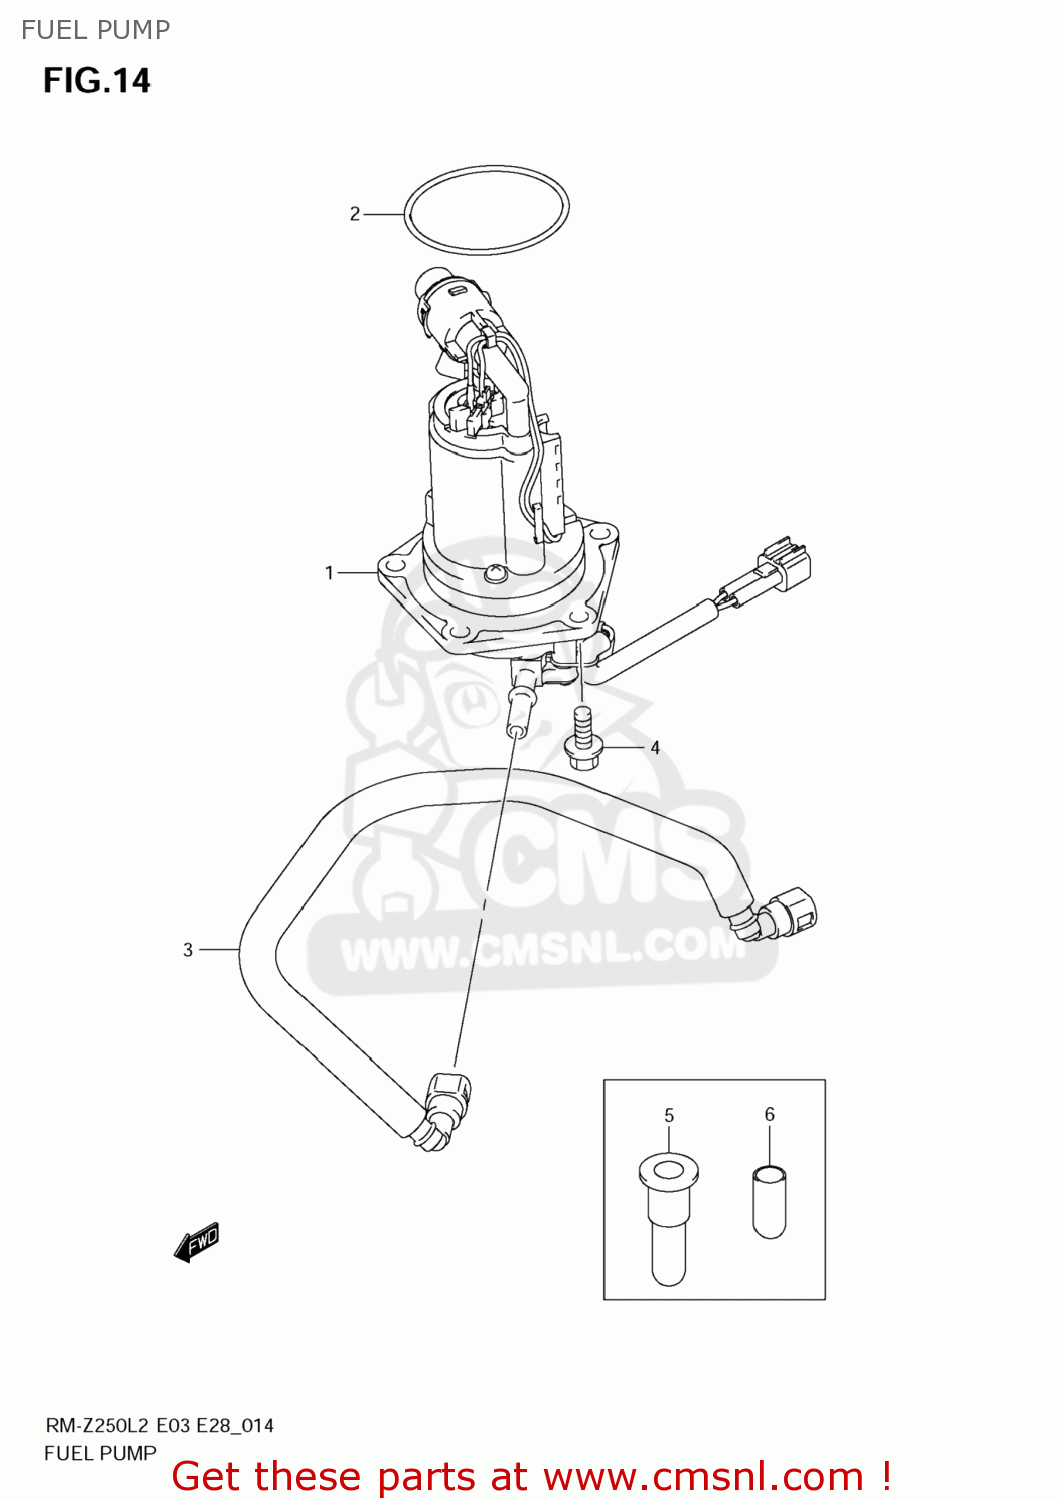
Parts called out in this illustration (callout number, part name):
1	PUMP ASSY,FUEL
2	O RING
3	HOSE,FUEL
4	BOLT
5	CAP,FUEL HOSE
6	CAP,FUEL PUMP
